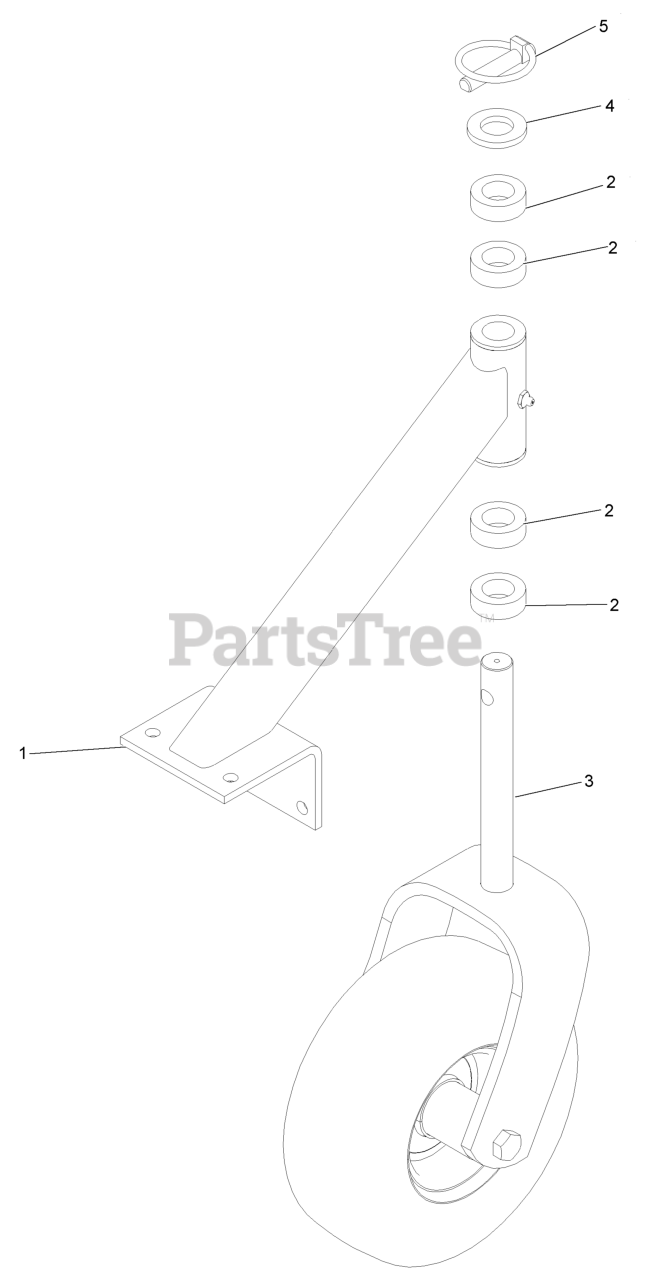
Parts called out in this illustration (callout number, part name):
1	SUPPORT ASM
2	SPACER-CASTER
3	ASM,CASTER/WHEEL
4	WASHER-FLAT
